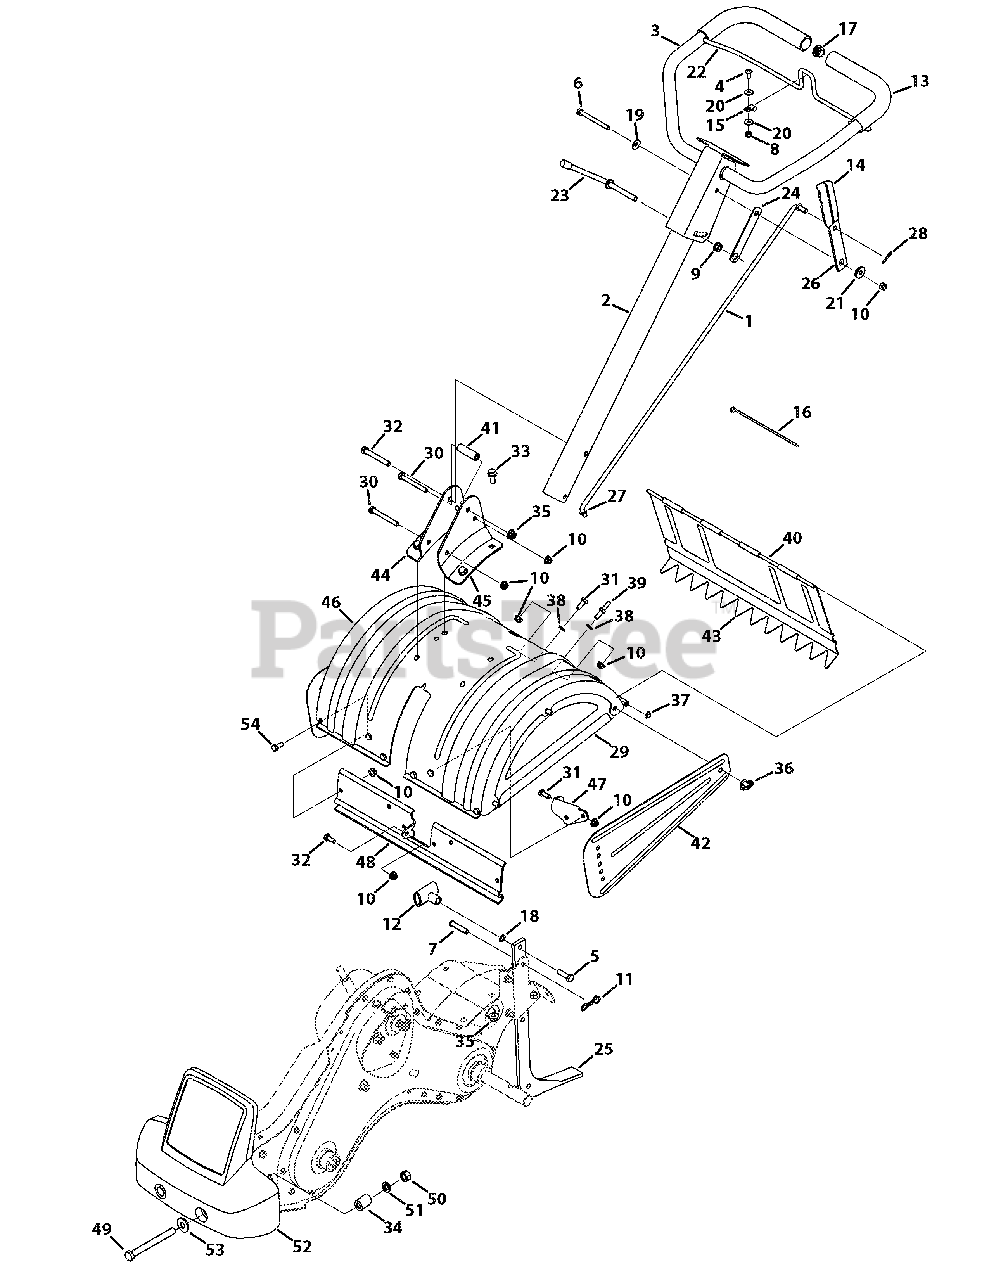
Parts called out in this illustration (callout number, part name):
1	Shift Rod
2	Lower Handle Tube Assembly
3	Upper Handle Assembly
4	Screw, 1/4-20 x 0.625
5	Hex Screw, 3/8-16:1.25
6	Hex Screw, 5/16-18 x 3.25
7	Clevis Pin, .375 X 1.75
8	Hex Lock Nut, 1/4-20
9	Flange Lock Nut, 3/8-24
10	Hex Lock Nut, 5/16-18
11	Cotter Pin
12	Small Tee Knob
13	Foam Grip, .970 x 11.0
14	Grip, .1875 x 1.00
15	Battery Clamp, 5/16
16	Cable Tie, 8.5
17	End Plug
18	Flat Washer, .385 x .620 x .033
19	Bell Washer, .340 x .872 x .060
20	Flat Washer, .260 x .720 x .060
21	Spacer, .50 x .190 x .360
22	Clutch Bail
23	Handle Adjustment Crank
24	Hex Nut Retainer Bracket
25	Tiller Depth Control
26	Shaft Rod Lever
27	Washer, .33 x .87 x .125
28	Cotter Pin, .072 x 1.12
29	End Cover Assembly
30	Hex Screw, 5/16-18 x 2.75
31	Hex Screw, 5/16-18 x 1.00
32	Hex Screw, 3/8-16 x 2.75
33	Hex Flange, 3/8-16 x .875
34	Hub, .636 x 1.00 x .94
35	Flange Lock Nut, 3/8-16
36	Wing Nut, 5/16-18
37	Speed Nut Cap, 1/4
38	Flat Washer, .344 x .62 x .033
39	Screw, Hex, 5/16-18 x .75
40	Tiller Flap Rod
41	Spacer, .322 x .625 x 2.00
42	Side Shield
43	Rear Tine Shield
44	RH Handle Mount Bracket
45	LH Handle Mount Bracket
46	Tine Shield
47	FRT Tine Shield Bracket
48	FRT Tine Shield Spacer Bracket
49	Hex Screw, 1/2-20 x 5.50
50	Hex Lock Nut, 1/2-20
51	Flat Washer, 1/2 x 1.25 x .10
52	Counterweight
